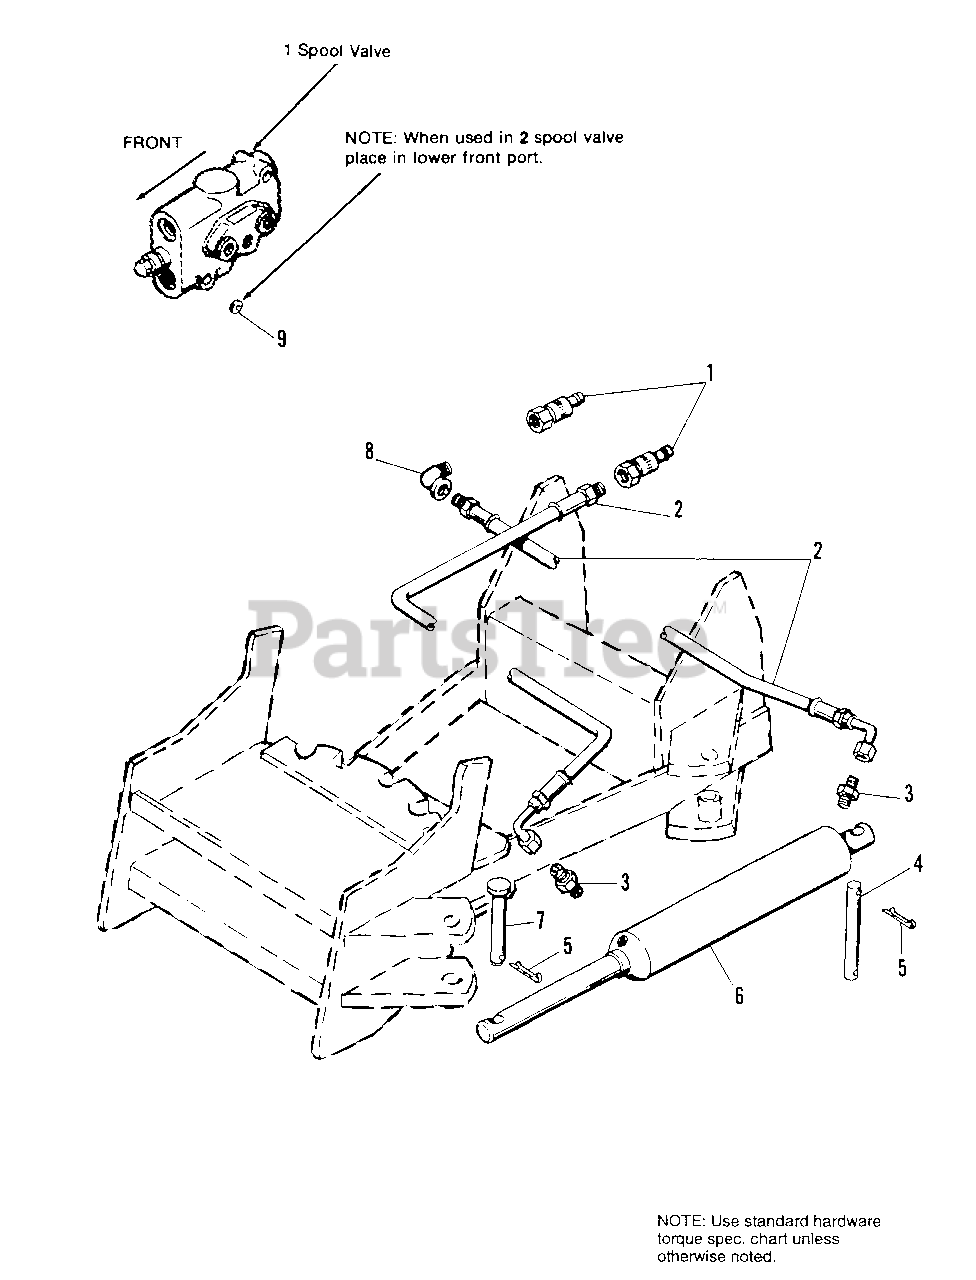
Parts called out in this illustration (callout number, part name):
1	NOSE PIECE ASSY.
2	HOSE ASSY., Hyd.
3	FITTING, Male
4	PIN, Cylinder
5	PIN, Cotter, 1/8 x 1 Lg.
6	CYLINDER ASSY.
8	ELBOW, Street, 90
9	WASHER, Restrictor
